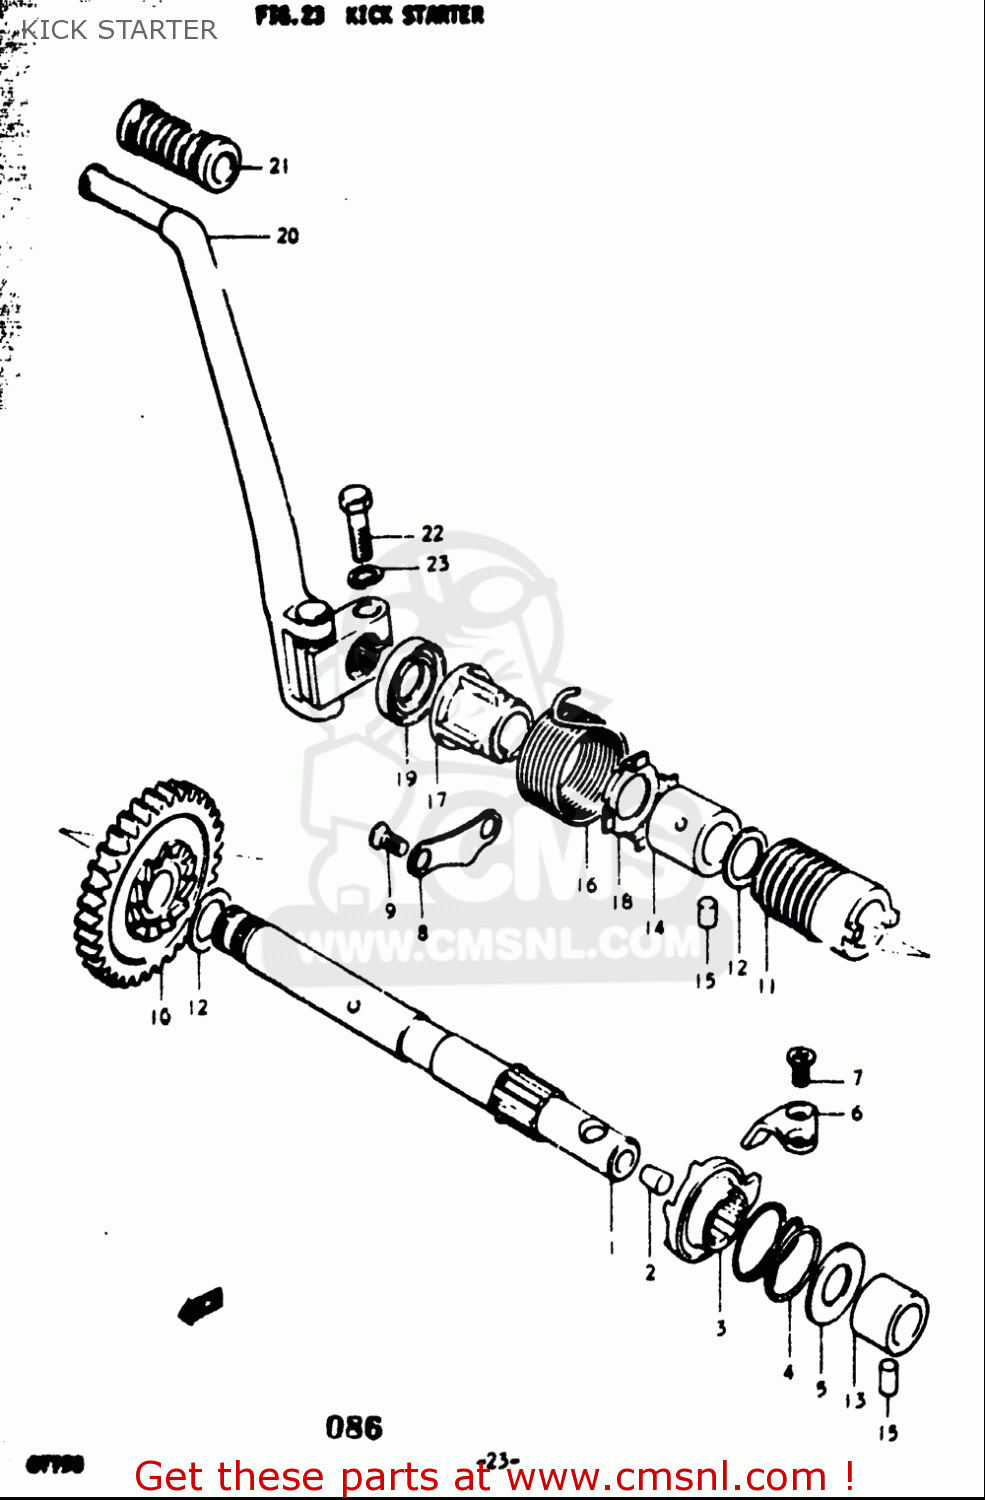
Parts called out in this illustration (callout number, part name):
2	PLUG
3	STARTER,KICK
4	SPRING
5	WASHER
6	GUIDE,KICK STARTER
7	SCREW
9	SCREW
12	SHIM(20X28X1)
15	PIN
16	SPRING
18	HOLDER,KICK SHAFT SPRING
19	SEAL,OIL(20X37X7)
20	LEVER ASSEMBLY,KICK STARTER
21	RUBBER,KICK STARTER PEDAL
22	BOLT
23	WASHER,LOCK
